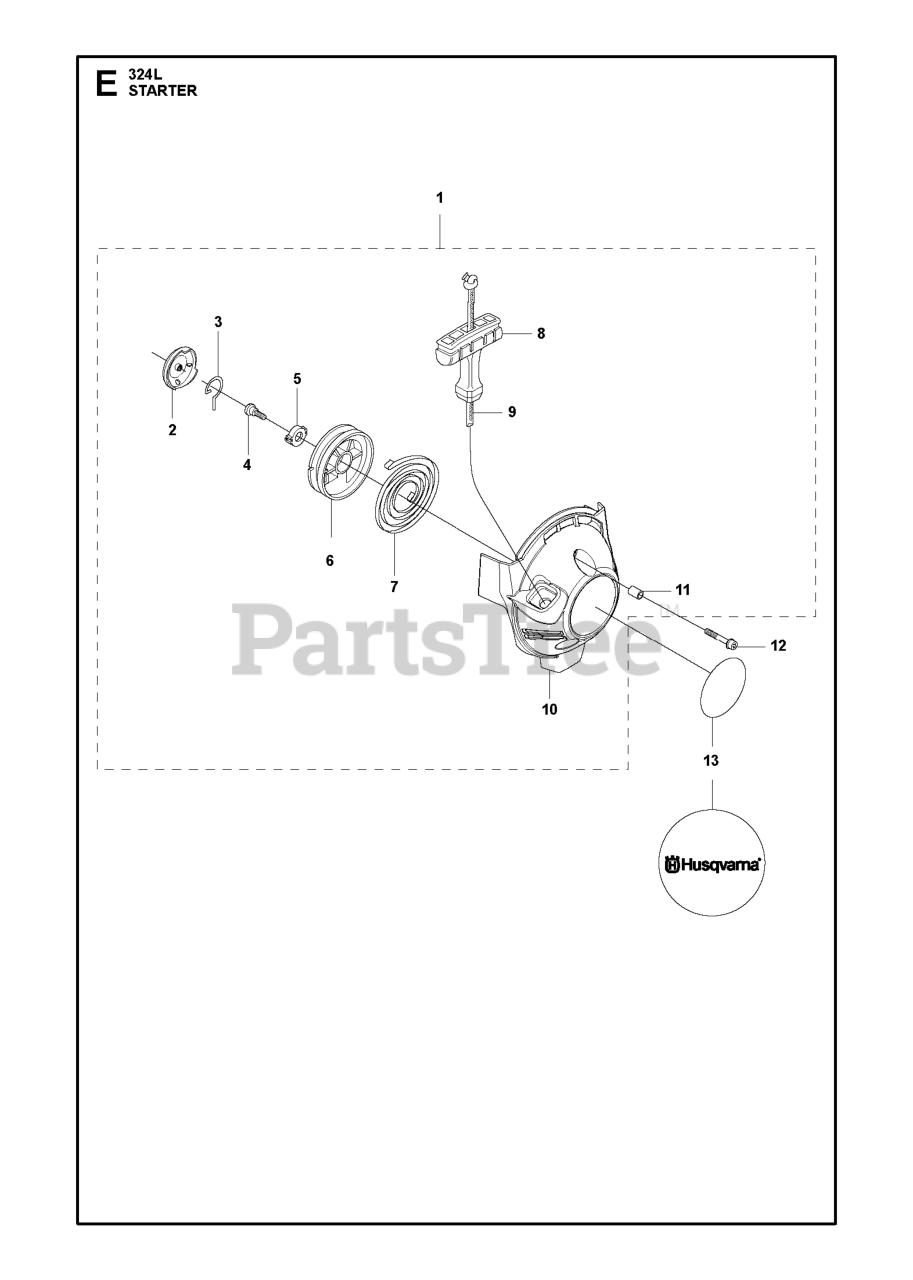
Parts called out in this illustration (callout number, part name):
1	STARTER DEVICE
6	STARTER PULLEY
7	RETURN SPRING
8	STARTER HANDLE
9	STARTER ROPE
10	STARTER HOUSING
